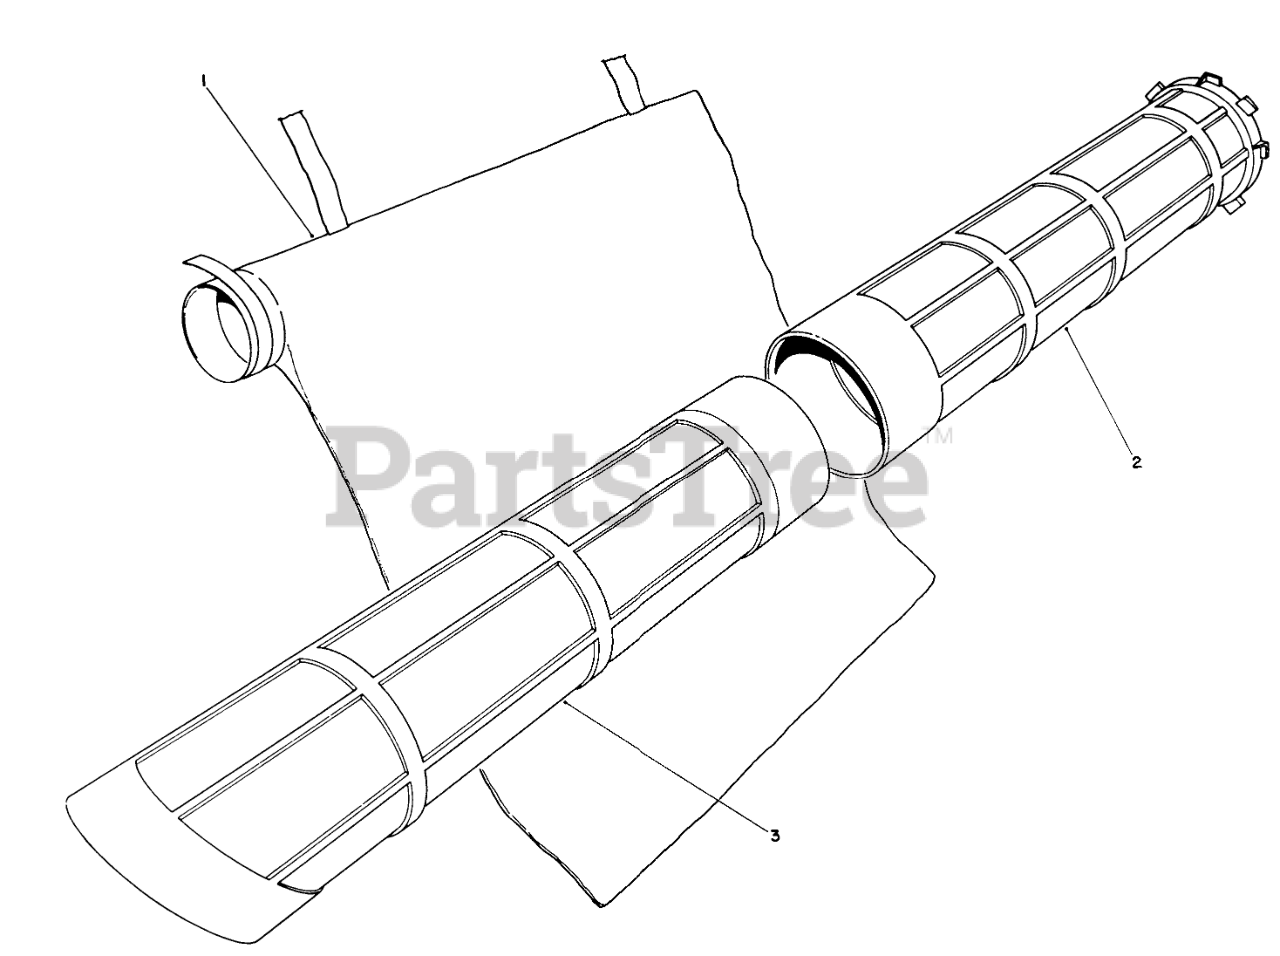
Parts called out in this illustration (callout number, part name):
1	VACUUM BAG
2	Tube-Upper Vacuum
3	Tube-Lower Vacuum
